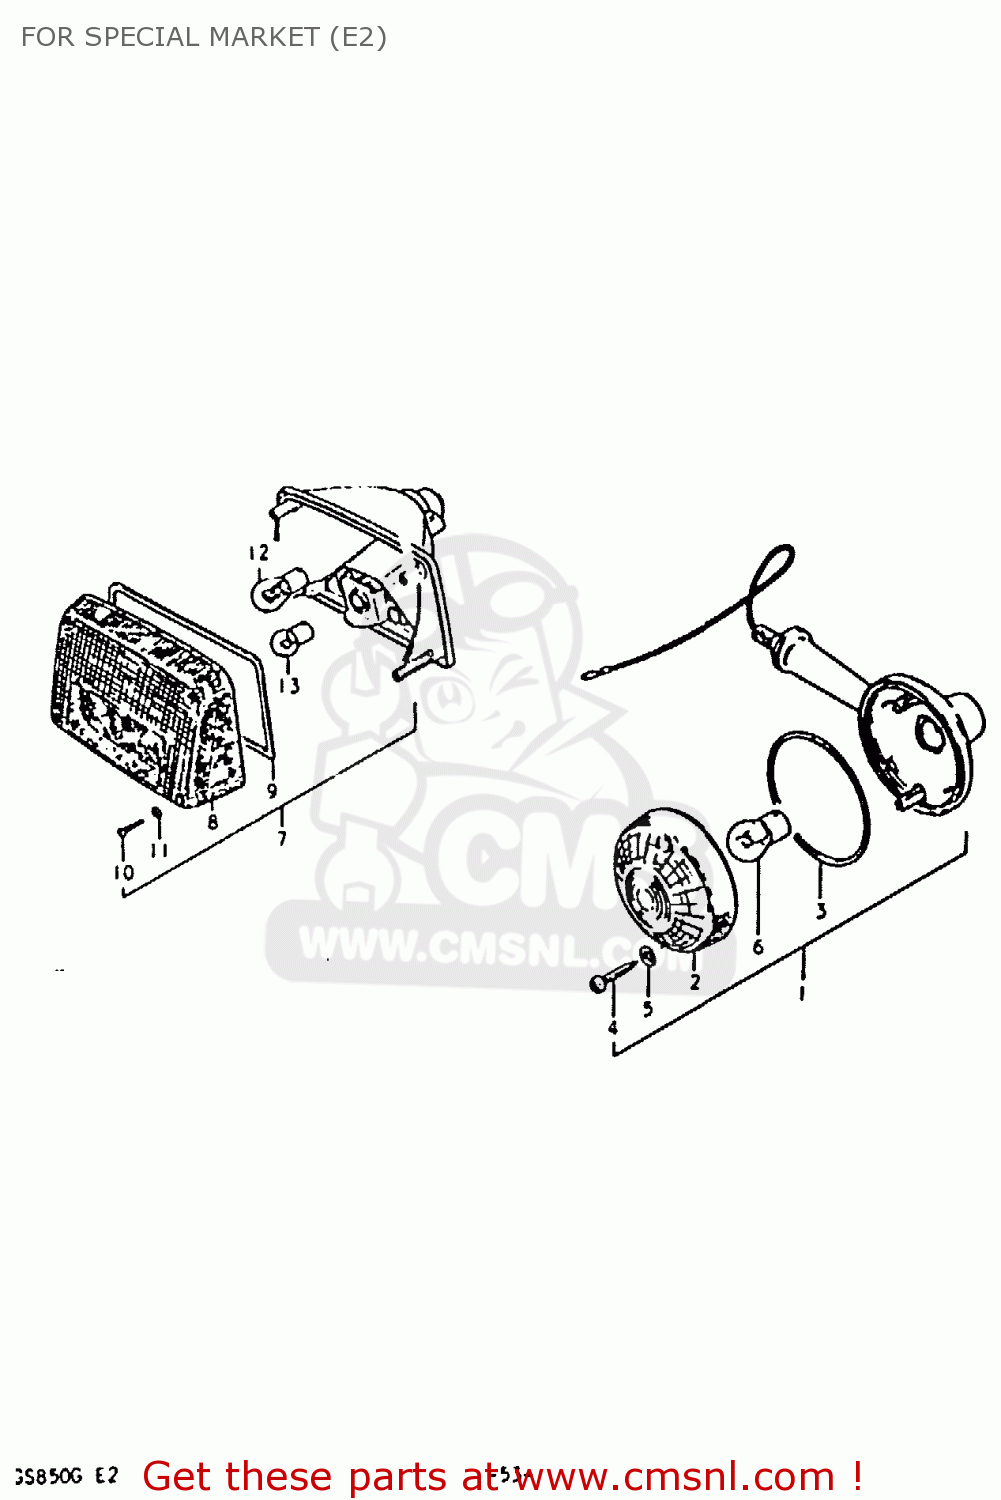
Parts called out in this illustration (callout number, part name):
1	LAMP ASSY, FRONT TURN SIGNAL
2	LENS
3	GASKET (NAS)
4	BOLT
5	GASKET (NAS)
6	BULB 12V 21W
7	LAMP ASSY, REAR COMBINATION
8	LENS
9	GASKET (NAS)
10	SCREW
11	GASKET (NAS)
12	BULB 12V21/5W
13	BULB
